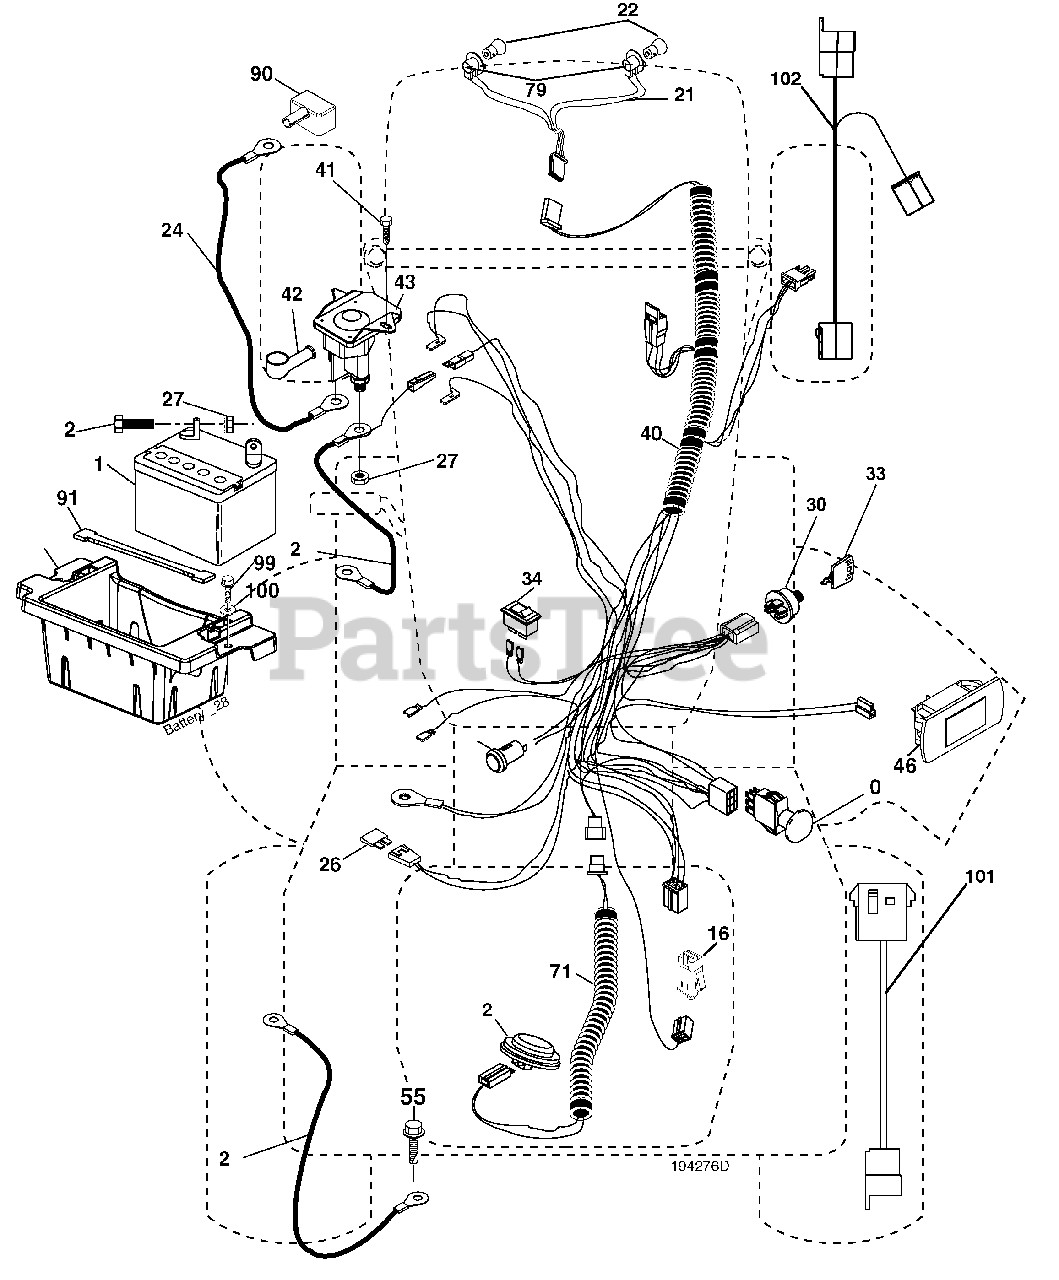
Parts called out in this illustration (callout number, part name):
1	Battery
2	Bolt Hex Head 1/4-20 x 3/4
8	Box Battery
16	Switch Interlock Push-In
21	Harness Socket Light W/4152J
22	Bulb Light
24	Cable Battery
25	Cable Start Red 17.5"
26	Fuse
27	Nut Keps Hex 1/4-20 unc
28	Cable, Ground
29	Switch, Seat
30	Switch, Ignition
33	Key, Ignition
34	Switch Light / Reset
40	Harness Ign. Dash
41	Screw Thd Cut 1/4-20 x 1/2
42	Cover, Terminal
43	Solenoid
46	Gauge Hourmeter
50	Switch, PTO
55	Screw Thdrol 5/16-18 x 3/4 TYTT
59	Outlet 12-Volt
71	Harness Ignition Chassis
79	Bulbholder Asm. Incan Descent
90	Cover Terminal Battery
91	Strap Battery Mount Front
99	Screw Hexwsh Thdrol 1/4-20 x 3/4
100	Washer 9/32 x 7/8 x 16 Ga.
101	Pigtail MATNLK
102	Harness Pigtail 12V Outlet
